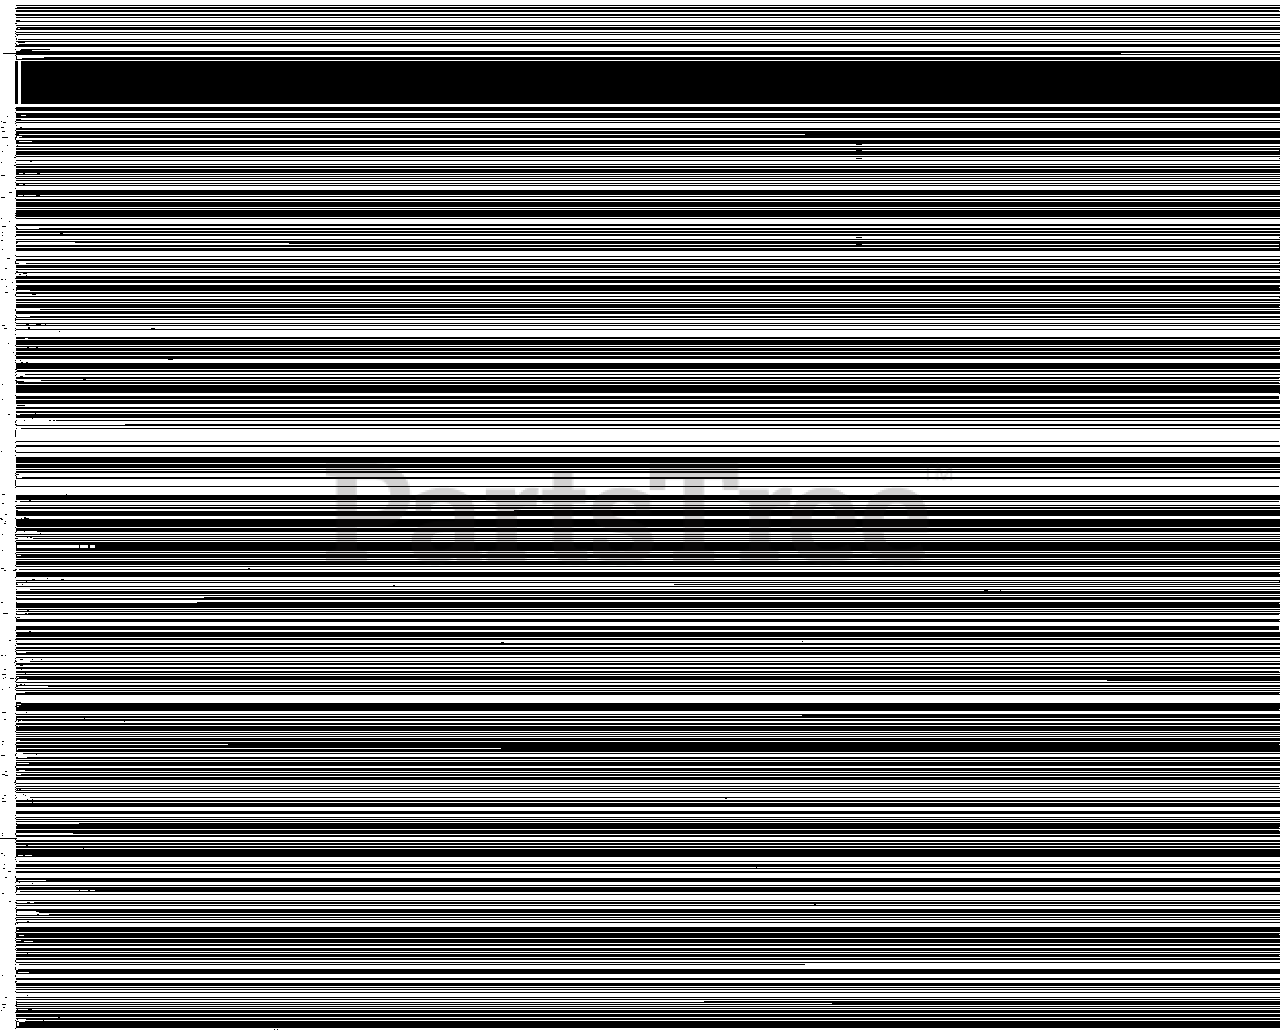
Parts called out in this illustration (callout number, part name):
1	BOLT SLPW 5×14
2	ENGINE COVER
3	BOLT M5×30
4	CRANKCASE M
5	OIL SEAL
6	BALL BEARING 6202 C3
7	CRANKCASE S
8	LOCATING PIN Ø5×10
9	FAN COVER
10	BOLT SPW M5×20
